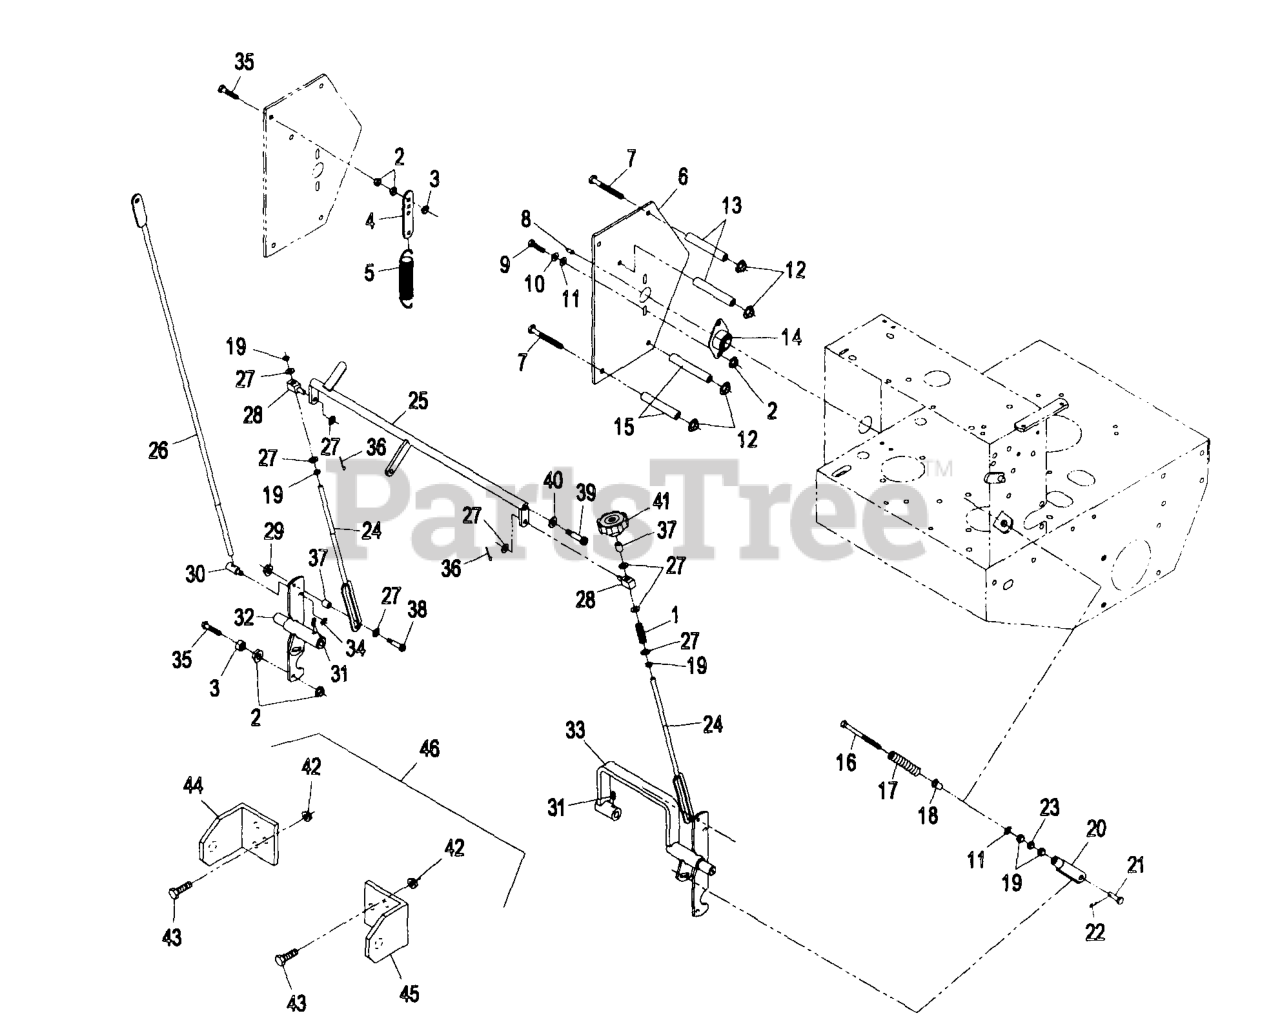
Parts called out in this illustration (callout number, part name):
1	SPRING-COMPRESSION
4	TAB-SPRING, EXTENSION
5	SPRING-EXTENSION
10	WASHER-LOCK
13	SPACER-SHIELD
14	BEARING-FLANGE, SIDE
15	SPACER-SHIELD
16	BOLT-RETURN, NEUTRAL
17	SPRING-RETURN, NEUTRAL
18	BUSHING-FLANGED
20	YOKE-ADJUSTABLE
21	PIN-CLEVIS
22	PIN-COTTER
24	LINK-CONTROL, SPEED
25	CRANK-CONTROL, SPEED
26	ROD-LEVER, DRIVE
31	SCREW-SET
38	SCREW-HSH
39	SCREW-HSH
41	KNOB-TRACKING
45	BRACKET,SULKY RH
46	Sulky Kit
47	BOLT-TAP, HH
